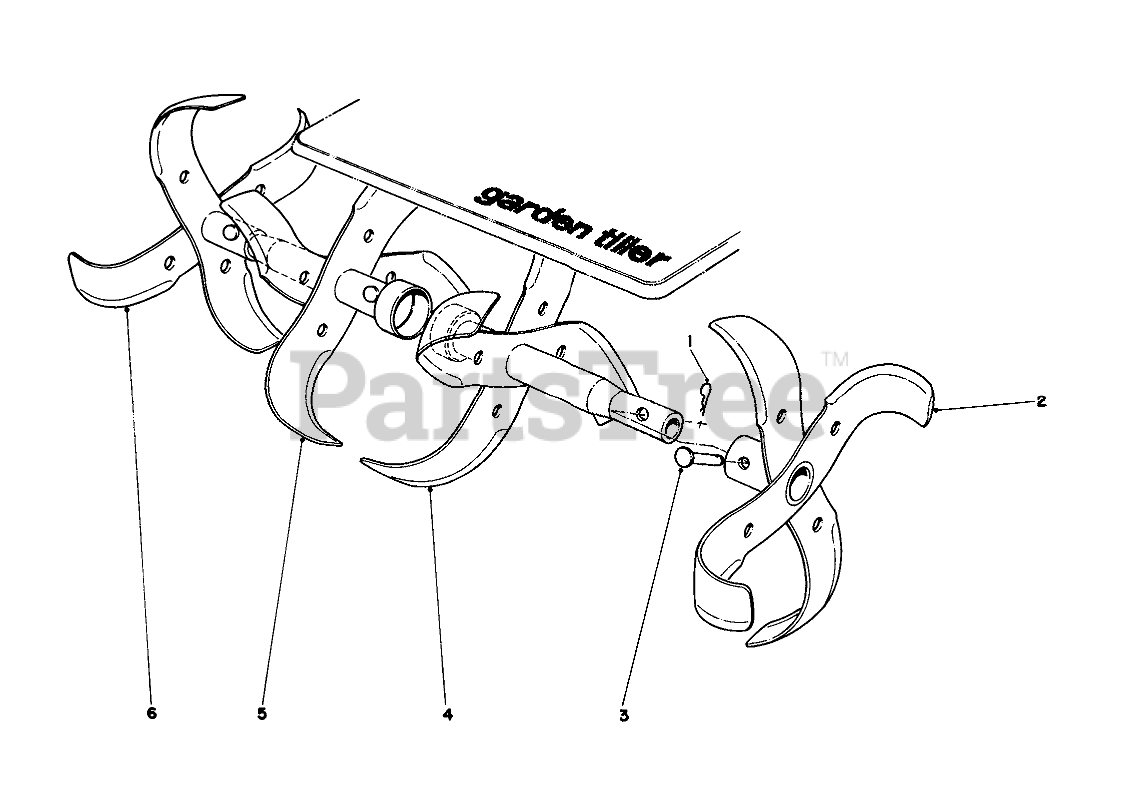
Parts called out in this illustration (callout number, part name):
1	PIN-COTTER
2	LH OUT SLASH TINE WA
3	TINE PIN
4	Inner Tine L.H.
5	Inner Tine R.H.
6	RH OUT SLASH TINE EA
